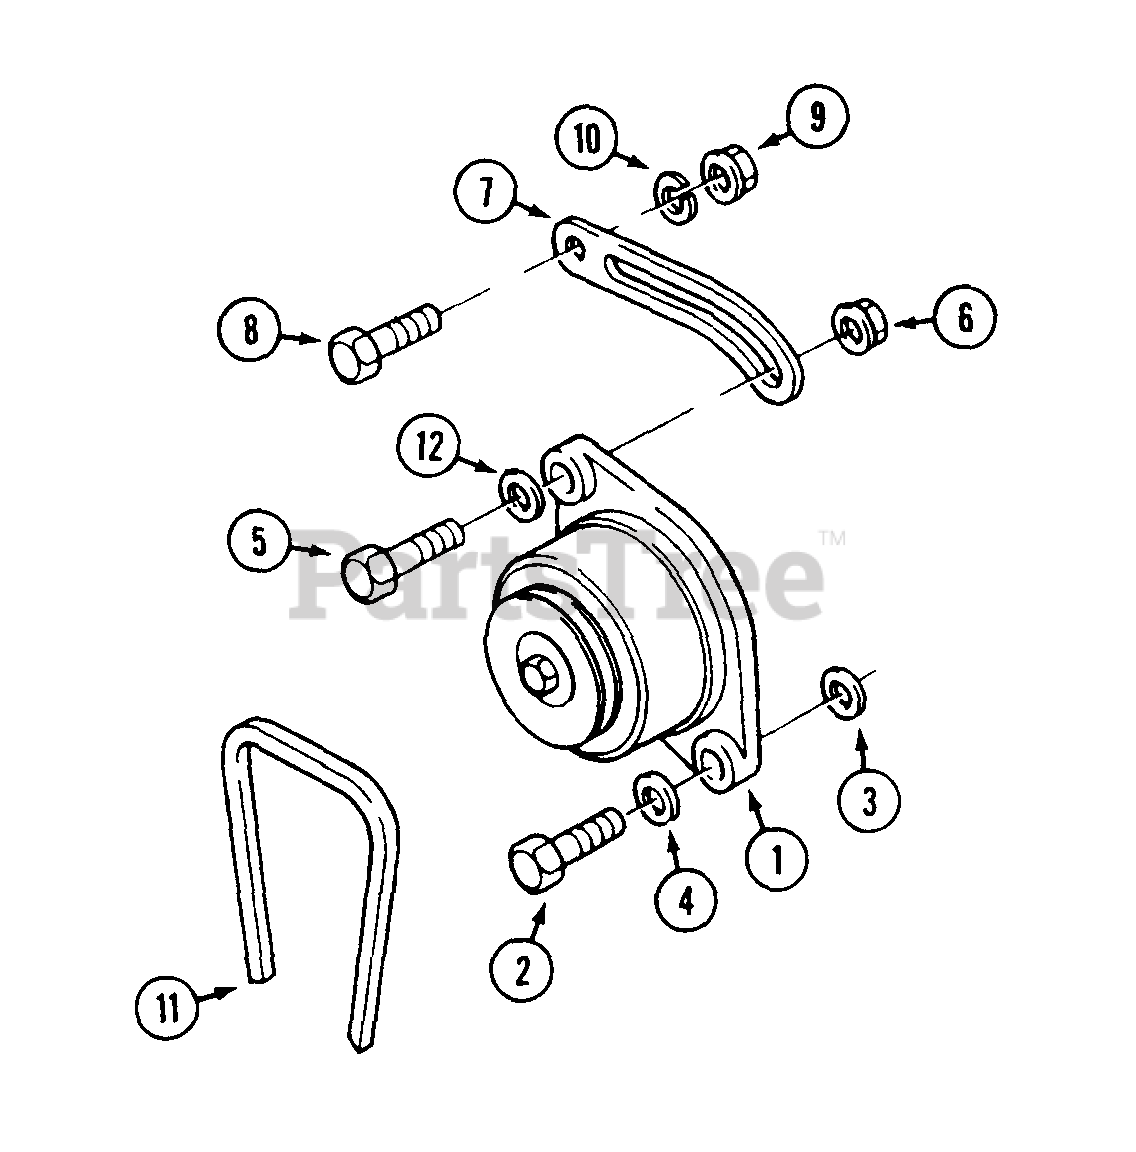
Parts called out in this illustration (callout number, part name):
1	ALTERNATOR
2	SCREW
3	WASHER
4	WASHER
5	SCREW
6	NUT
7	LEVER
8	SCREW
9	NUT
10	WASHER
11	BELT
12	WASHER
